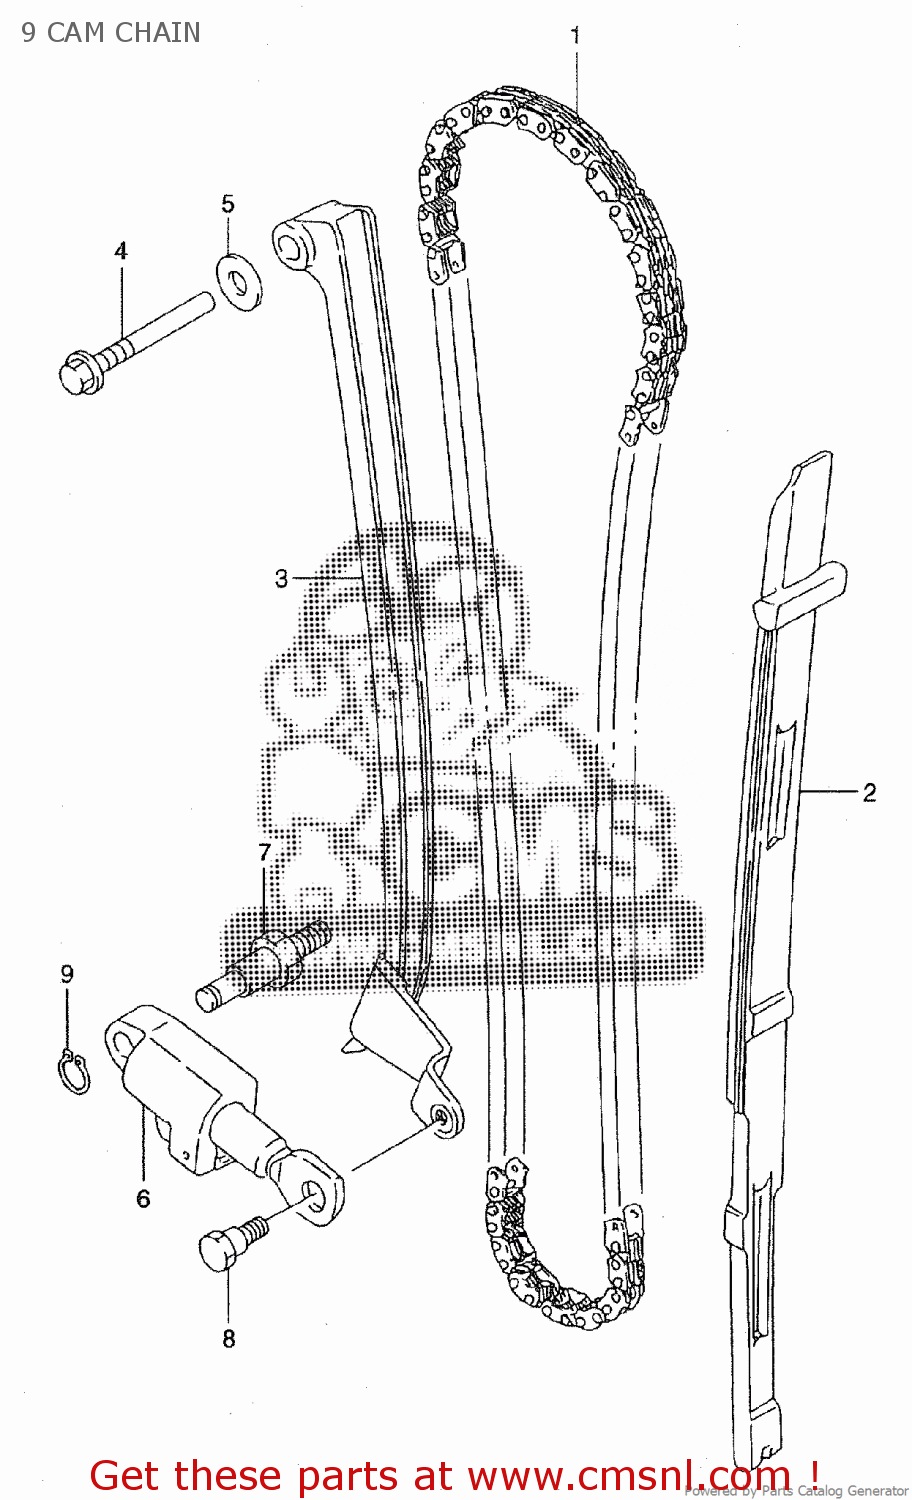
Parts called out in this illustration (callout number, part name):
1	CHAIN,CAMSHAFT DRIVE
2	GUIDE,CAM CHAIN
3	TENSIONER,CAM CHAIN
4	BOLT,CAM CHAIN TENSIONER
5	GASKET 8.2X14X1 (NAS)
6	ADJUSTER ASSY,TENSIONER
7	BOLT,STUD
8	BOLT
9	CIRCLIP
